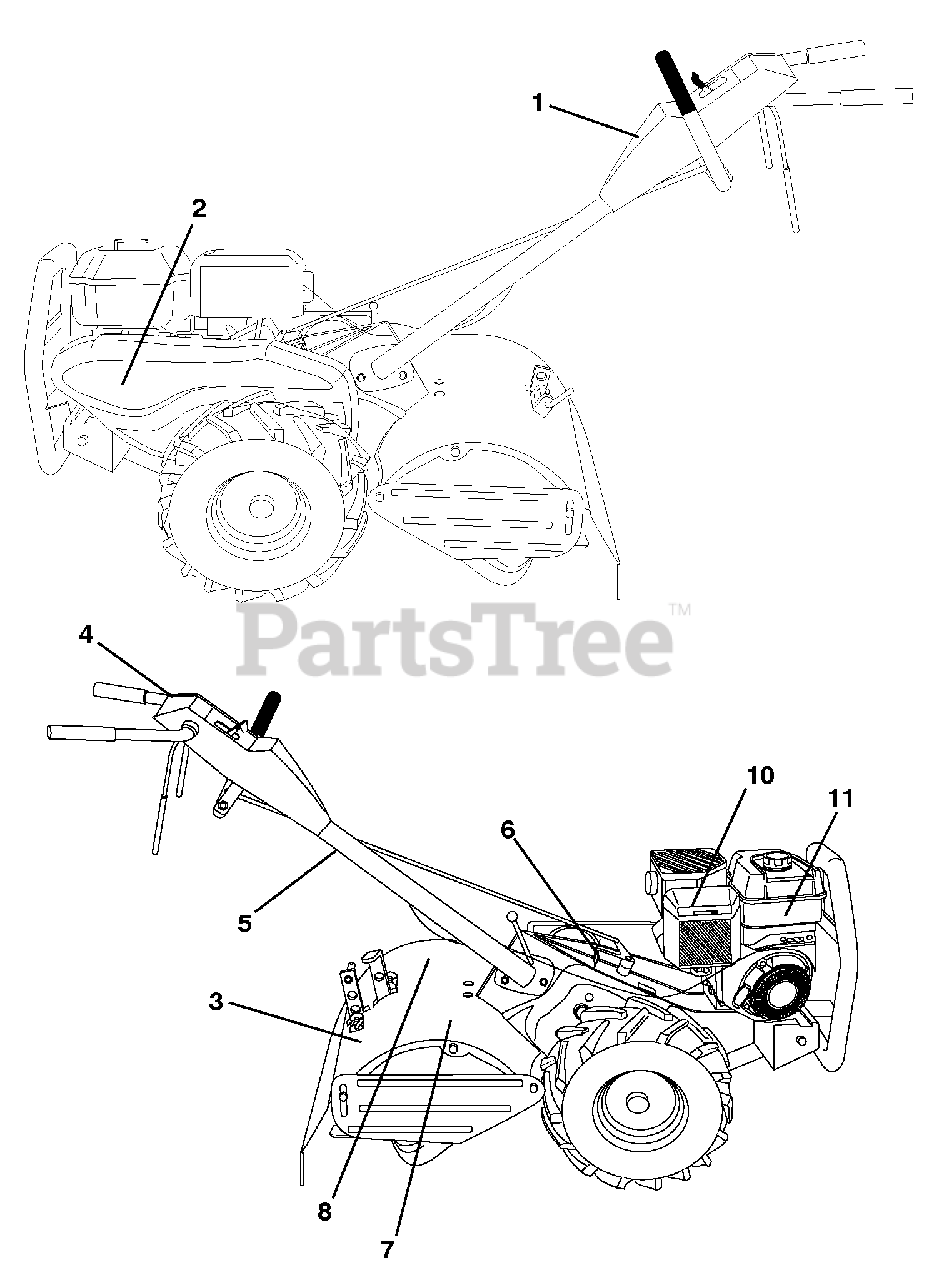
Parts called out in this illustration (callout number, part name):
1	Decal, Instruction, Tilling
2	Decal, Decal, Blt Grd
3	Decal, Warning
4	Decal, Console Instruction
5	Decal, Hand Placement
6	Decal, Shift Indicator
7	Decal, Rev Tine Shield
8	Decal, Fwd Tine Shield
10	Decal, Air Cleaner
11	Decal, Engine Tank
11	Manual, Operator's, English/French
11	Manual, Repair Parts, English/French
